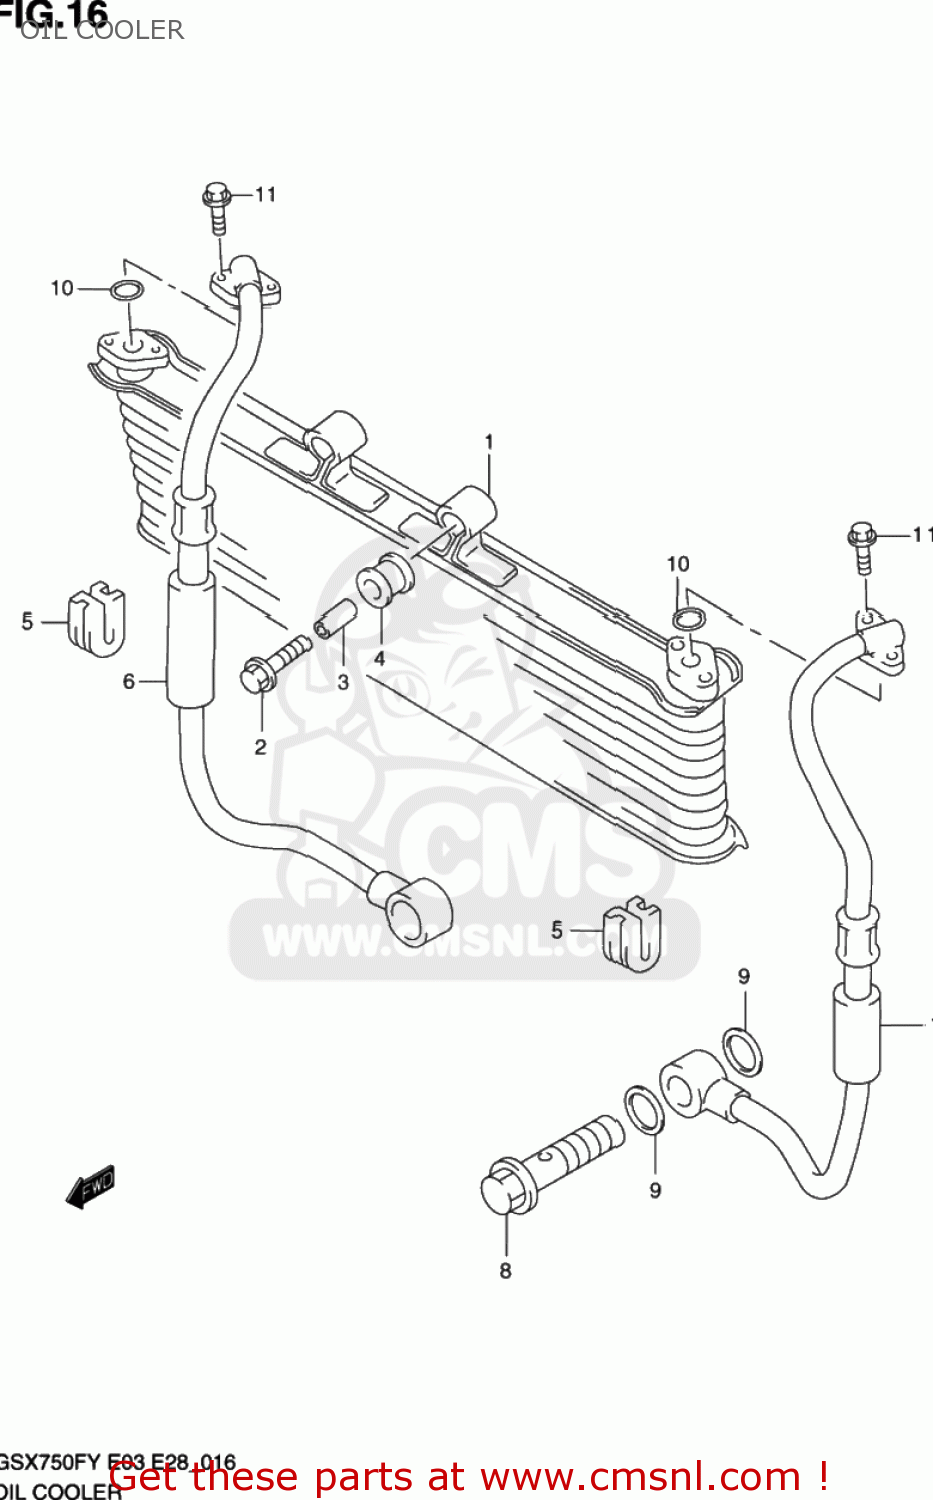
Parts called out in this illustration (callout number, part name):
1	COOLER ASSY,OIL
2	BOLT(8X40)
3	SPACER(8.5X12X25)
4	CUSHION,OIL COOLER NO.1
5	CUSHION,OIL COOLER NO.2
6	HOSE,OIL COOLER,R
7	HOSE,OIL COOLE
8	BOLT UNION
9	GASKET(16X22X2) (NAS)
10	O RING(D:2.4,ID:11.8)
11	BOLT,OIL FILLE
